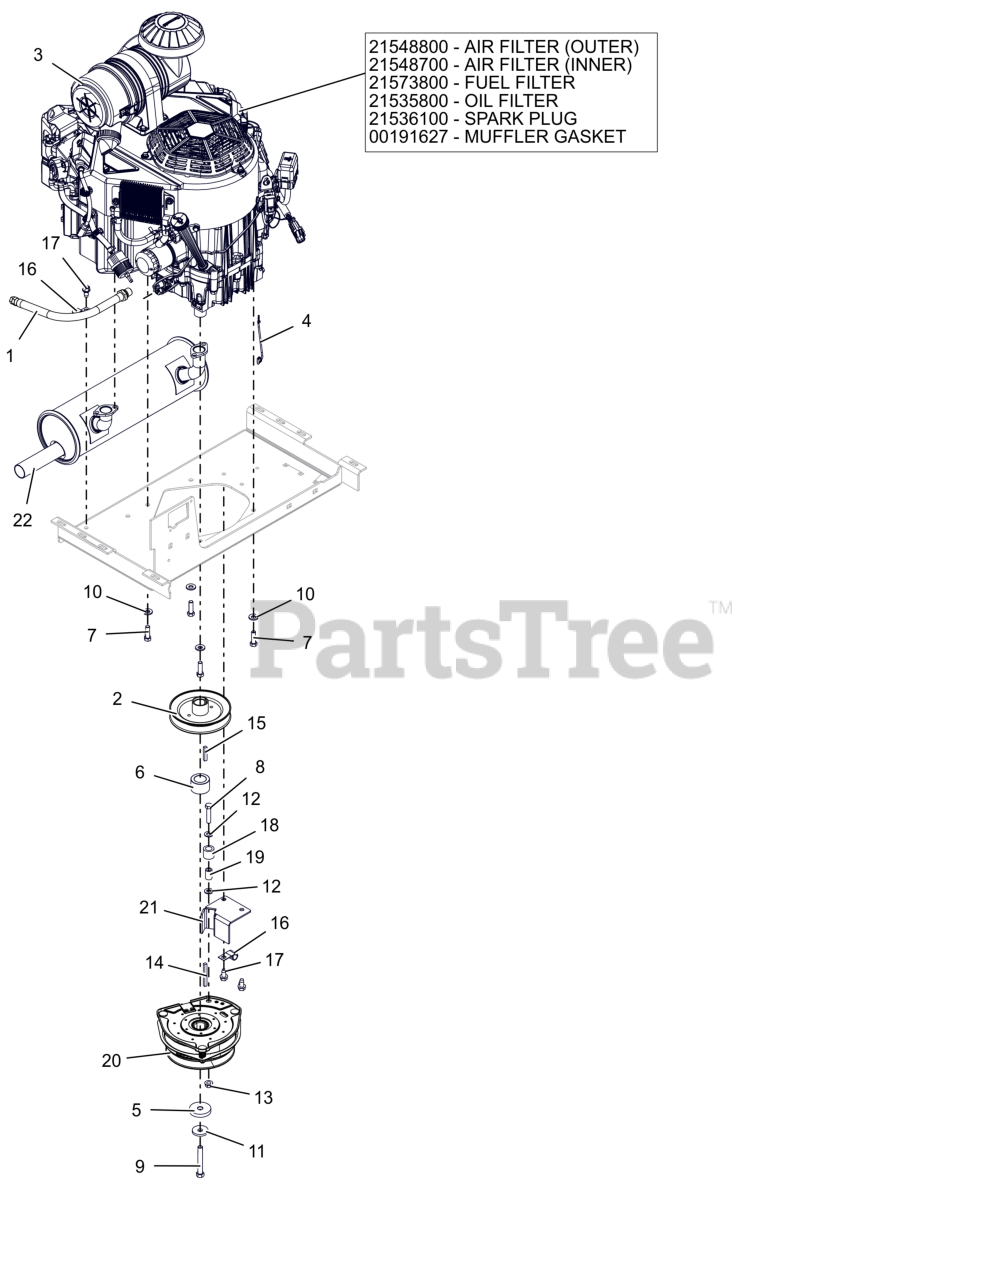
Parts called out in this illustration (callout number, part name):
1	HOSE, OIL DRAIN
2	WLDMT, TRANSAXLE DRIVE PULLEY
3	ENGINE, KAWASAKI - FX 850 EFI W/VOLT REG
3	FILTER, OUTER
3	FILTER, INNER - KAW
3	FUEL FILTER
3	FILTER,OIL - KAW
3	PLUG, SPARK
3	GASKET, MUFFLER S/O
4	LEAD - STARTER SOLENOID
5	SPACER, .474/.459X2.00X.350
6	SPCR, 1.125 x 1.750 x 1.147
7	BLT, HEX .38-16X1.25 G5 ZCC NT
8	BLT, HEX .38-16X1.75 G5 ZCC
9	BLT, HEX 0.4375-20X3 G8 ZCC NT
10	WASHER, 3/8" SPRING DISC
11	WASHER, 7/16" SPRING DISK
12	WSHR,FLT .406X.812X.065 ZCC
13	NUT-LK-CTR-FLG .375-16 GF ZCC
14	KEY-SQ .25 X 2.50 X .25 SAE
15	KEY-SQ .25 X 1.50 X .25 SAE
17	SCR,TAP .375-16X.75 HWH TR ZCC
18	BUMPER,RUBBER .62X1.0X.88 LG
19	BUSH.,S.391X.622X.950 ST
20	CLUTCH, OGURA GT3.5-AR04
21	WLDMT, CLUTCH STOP (BLACK)
22	MUFFLER, KAWASAKI FX850
